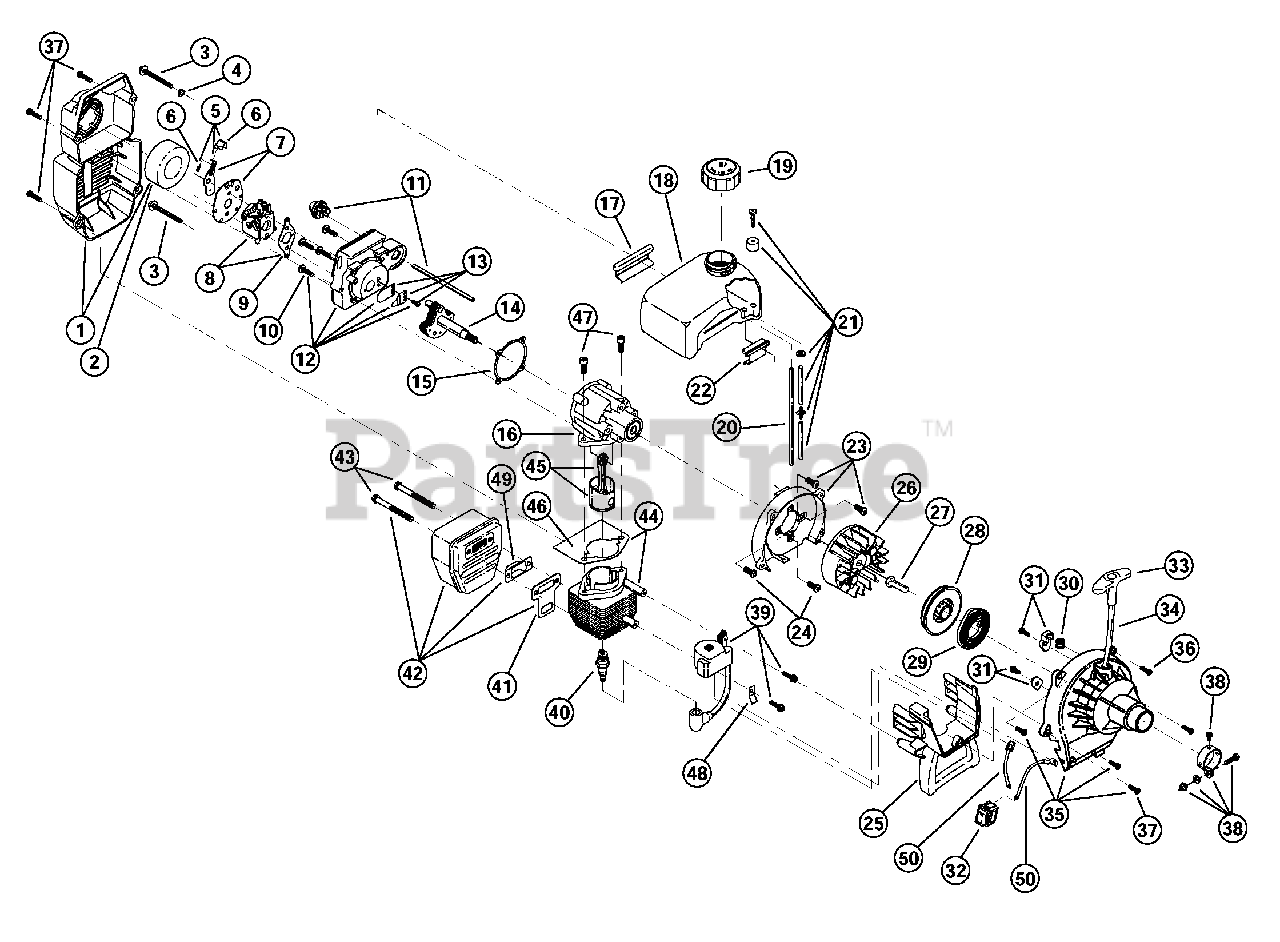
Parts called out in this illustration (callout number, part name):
1	Air Cleaner/Muffler Cover Assembly
2	Air Cleaner Filter
3	Carburetor Mounting Screw Assembly
4	Wavey Washer
5	Choke Lever Assembly
6	Choke Knob and Screw
7	Choke Lever and Plate
8	Carburetor Assembly W/Limiter Caps
9	Carburetor Gasket
10	Carb Mount Screw
11	Primer and Hose Assembly
12	Carb Mount Assembly
13	Reed Assembly
14	Power Shaft Assembly
15	Carburetor Mount Gasket
16	Crank Case Service Assembly
17	Rear Mounting Pad
18	Fuel Tank Assembly
19	Fuel Cap Assembly
20	Fuel Return Line
21	Fuel Line Assembly
22	Front Mounting Pad
23	Shroud Assembly
24	Shroud Screw
25	Shroud Extension and Stand
26	Flywheel Assembly
28	Recoil Pulley Assembly
29	Recoil Spring
30	Rope Guide
31	Pulley Retainer Assembly
32A	Positive Switch
32B	Momentary Switch
33	Pull Handle
35	Starter Housing Assembly
36	Housing Screw
37	Cover Screw
38	Upper Clamp Assembly
39A	Governed Module Assembly
39B	Pulse Module Assembly
40	Spark Plug
41	Exhaust Gasket
42	Muffler Assembly
43	Muffler Mounting Bolt Assembly
44	Cylinder Assembly
45	Piston and Rod Assembly
46	Cylinder Gasket
47	Cylinder Bolt
48	Male Tab
49	Spark Arrestor
50	Lead Wires
